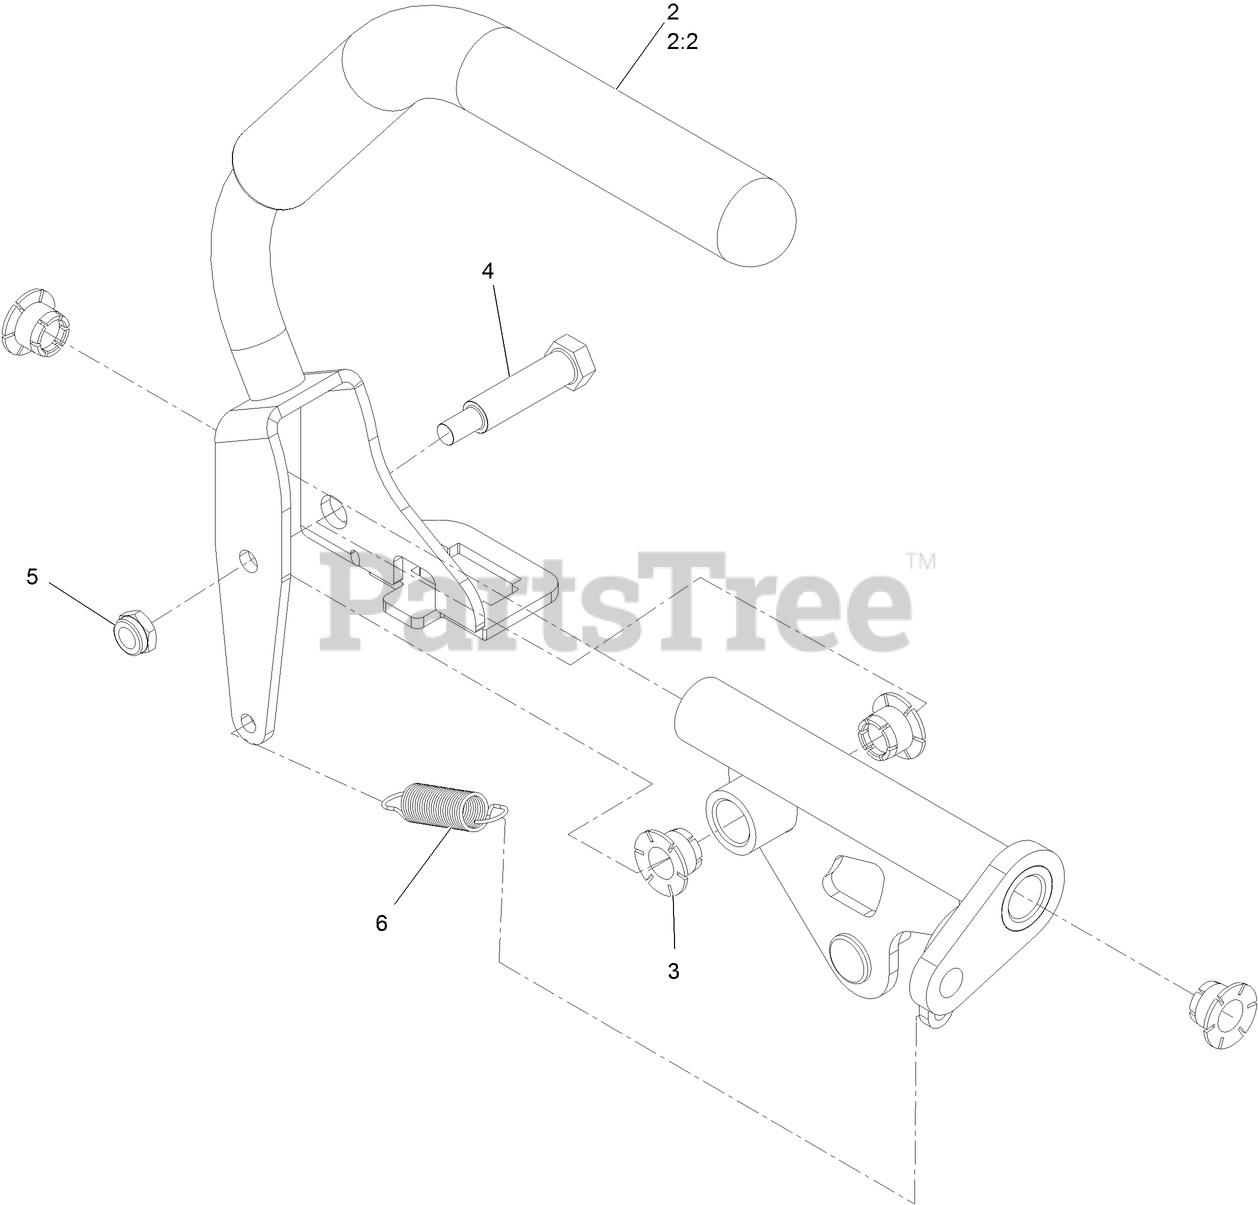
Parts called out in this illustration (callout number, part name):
2	ASM, LT CONTROL LEVER W/ GRIP
2:2	GRIP, DRIVE LEVER
3	BEARING, IGUS
4	BOLT-SHOULDER
5	NUT-LOCK, NI
6	SPRING-EXTENSION
